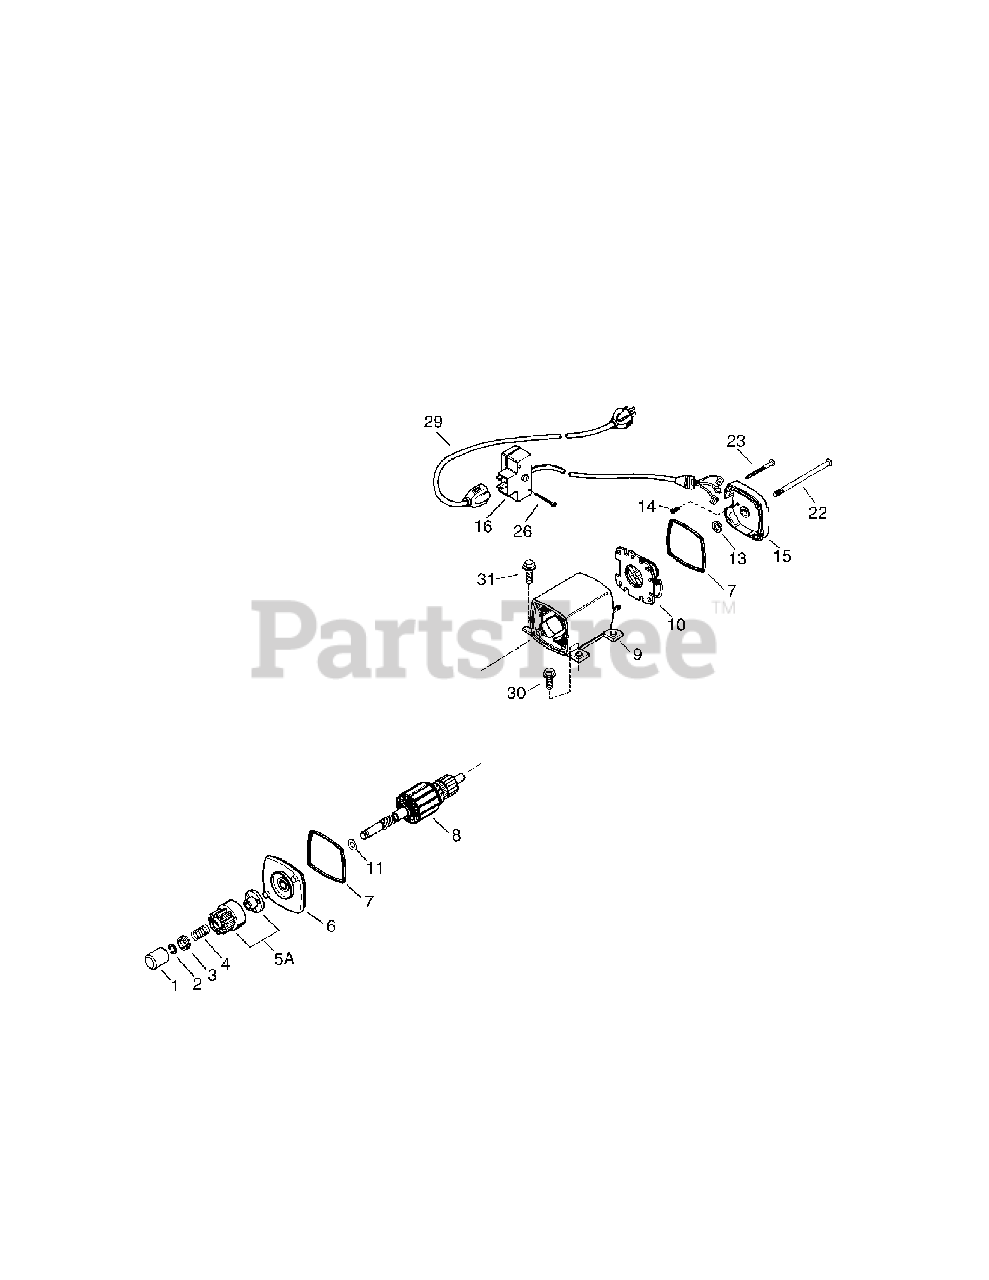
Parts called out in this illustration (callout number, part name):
1	Dust Cover
2	Retainer Ring
3	Spring Retainer
4	Anti-Drift Spring
5A	Gear & Nut
6	Drive End Cap Assy.
9	Housing Assy.
10	Brush Card Assy.
11	Thrust Washer
13	Thrust Washer
14	Ground Screw
15	Commutator End Cap Assy.
16	Switch Box Assy.
22	Case Bolt
23	Ground Screw
26	Screw (6-32x2-1/2")
29	Extension Cord
30	Screw (T-30)
31	Screw (1/4-20x1/2")
